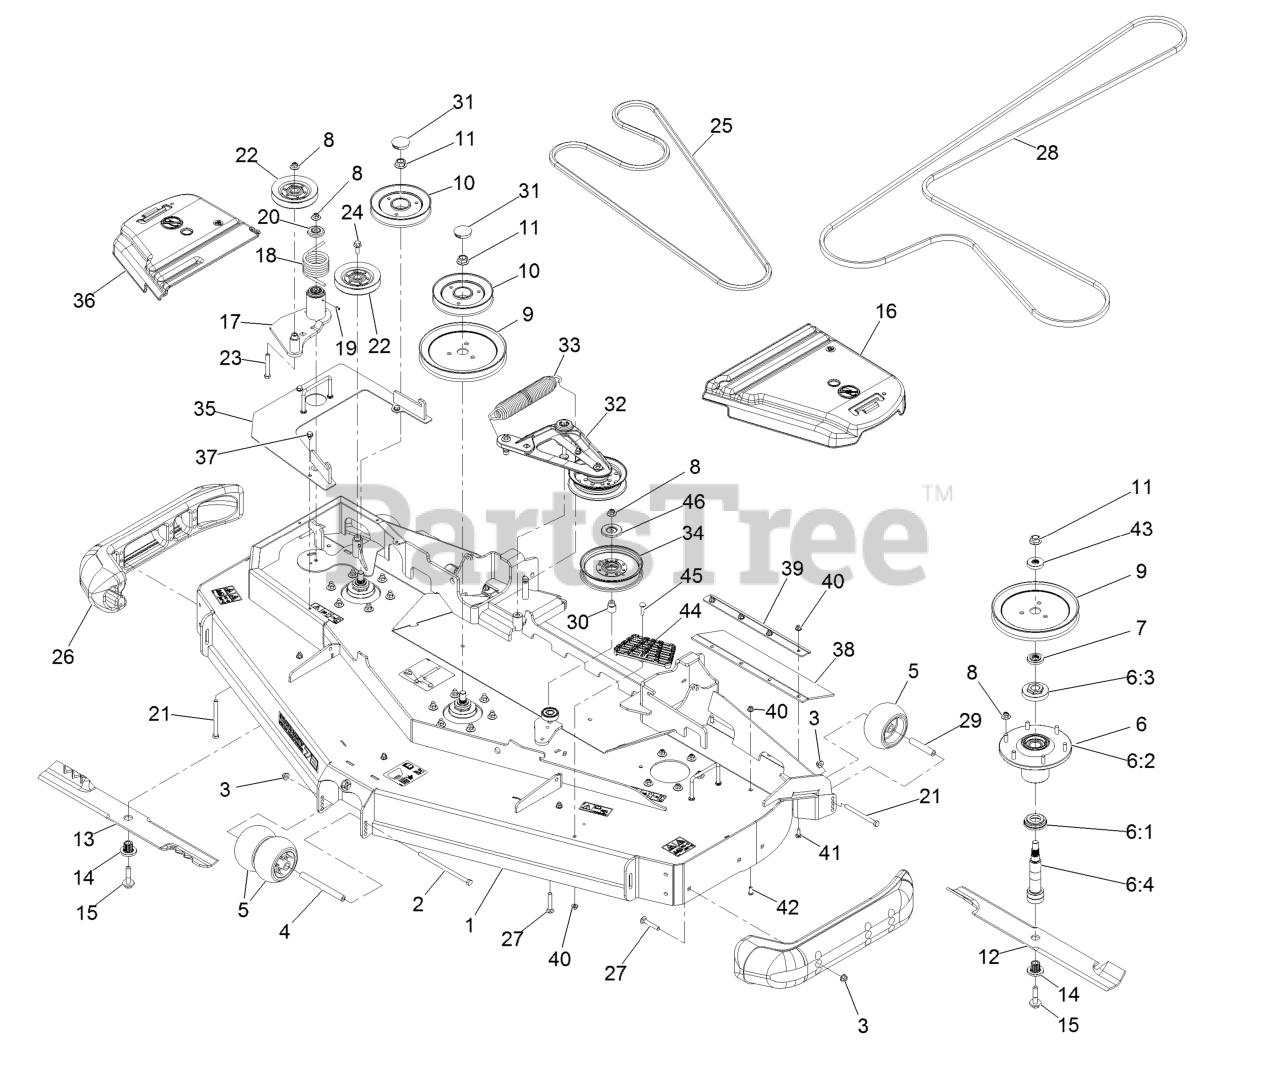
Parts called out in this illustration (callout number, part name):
1	Deck-Rd72 Nlz, W/Decals
2	Screw-HH 3/8-16 X 7 3/8
3	Nut-Nyloc 3/8-16 Flg
4	Spacer-Wheel
5	Roller-Scalp, Anti
6	ASM,Spindle Housing
6:1	Guard, Bottom
6:2	Asm, Cutter Housing
6:3	Nut, Spindle 7/8-14
6:4	Spindle,Double Spline
7	Spacer, Splined Stepped
8	Nut-Nyloc 3/8-16 Flg
9	Sheave,Blade Drive 9.00
10	Sheave-Rd, Reverse Drive
11	Nut-Flange 5/8-18 Centerlock
12	Blade, Low Lift (72")
12	Blade, Notched (72")
12	Blade-Extreme 2, 24.50"
13	Blade-Low Lift 24.50, Rd72
13	Blade-Extreme 2-24.50, Rd72
14	Bushing, Splined
15	Screw-Sems 1/2-20 X 2.19
16	Cover-Belt, LH
17	Idler ASM
18	Spring-Torsion
19	Zerk-1/4-28 Str
20	Guard-Top
21	Screw-HH 3/8-16 X 4-1/2
23	Screw-HH 3/8-16 X 2 3/4
24	Screw-HH Flg 3/8-16 X 1
26	Skid-Bumper, Deck
27	Bolt-Carriage 3/8-16 X 2 1/4
28	Belt
29	Tube-Spanner
30	Bushing, Idler
31	Plug,Black Nylon 1.75
32	Deck Idler ASM
33	Spring-Extension
34	Idler-Pulley, Flat 6.00X1.00
35	Cover-Reverse Drive
36	Cover-Belt, RH
37	Screw-HWH 5/16 X 1/2 Tf
38	Guard-Tire
39	Support-Outer Flap
40	Nut-Nyloc 5/16-18 Flg
41	Bolt-Carriage 5/16-18 X 7/8
42	Screw-Button Head 5/16-18 X 3/4
43	Spacer, Splined
44	Step-Deck
45	Bolt-Carriage 5/16-18 X 1 1/4
46	Shield-Dust
